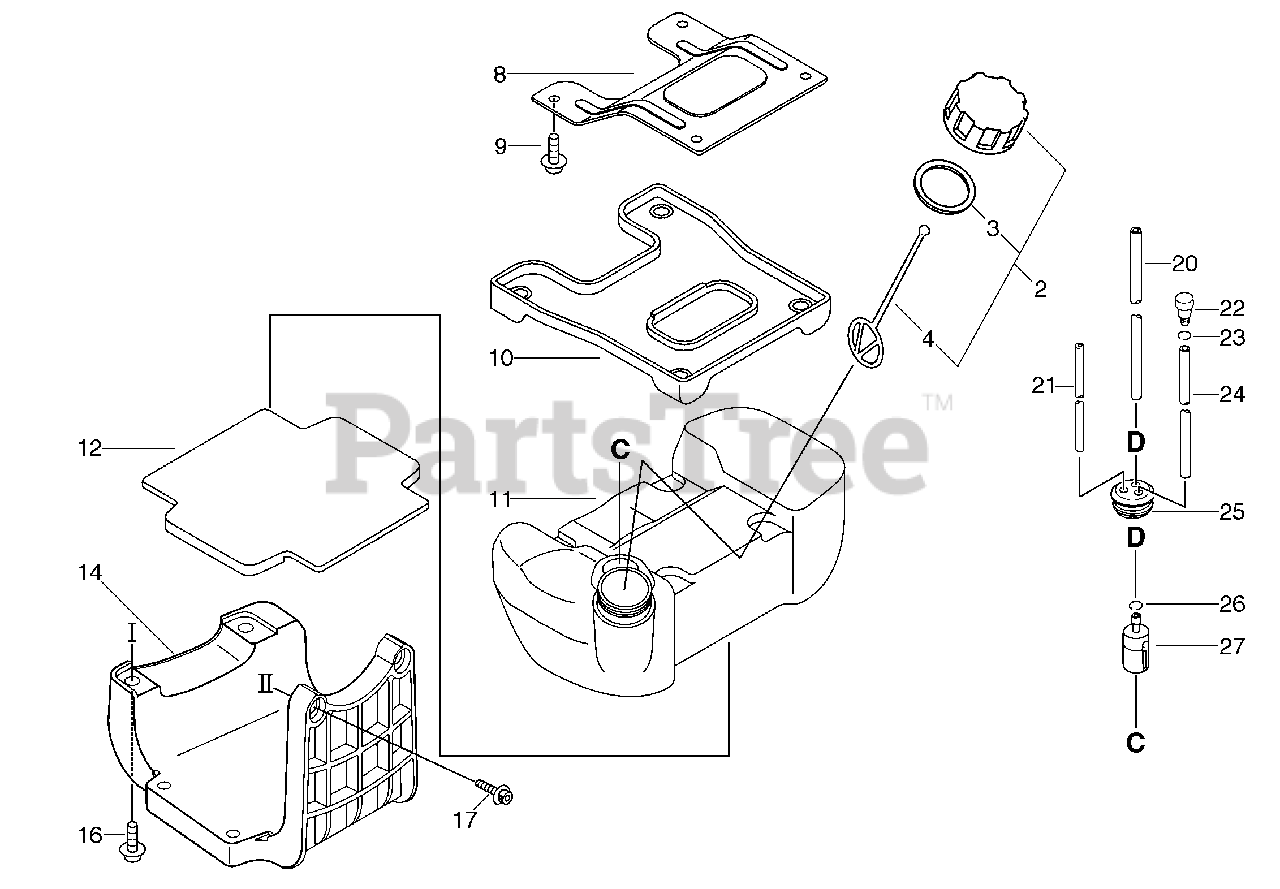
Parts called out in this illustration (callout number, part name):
2	CAP ASSY, FUEL
3	GASKET, FUEL CAP
4	CONNECTOR, CAP L= 100 MM
8	BRACKET, FUEL TANK
9	BOLT 5×12
10	CUSHION, UPPER
11	TANK, FUEL
12	CUSHION, FUEL TANK
14	GUARD, FUEL TANK
16	BOLT 5×20
17	BOLT 5×25
20	PIPE, FUEL 3×6×180 BLACK
21	PIPE, FUEL 3×6×60 CLEAR
22	VENT ASSY
23	CLIP 6.5 MM
24	PIPE, FUEL 3×6×120 BLACK
25	GROMMET, FUEL
26	CLIP 6.5 MM
27	FILTER, FUEL
